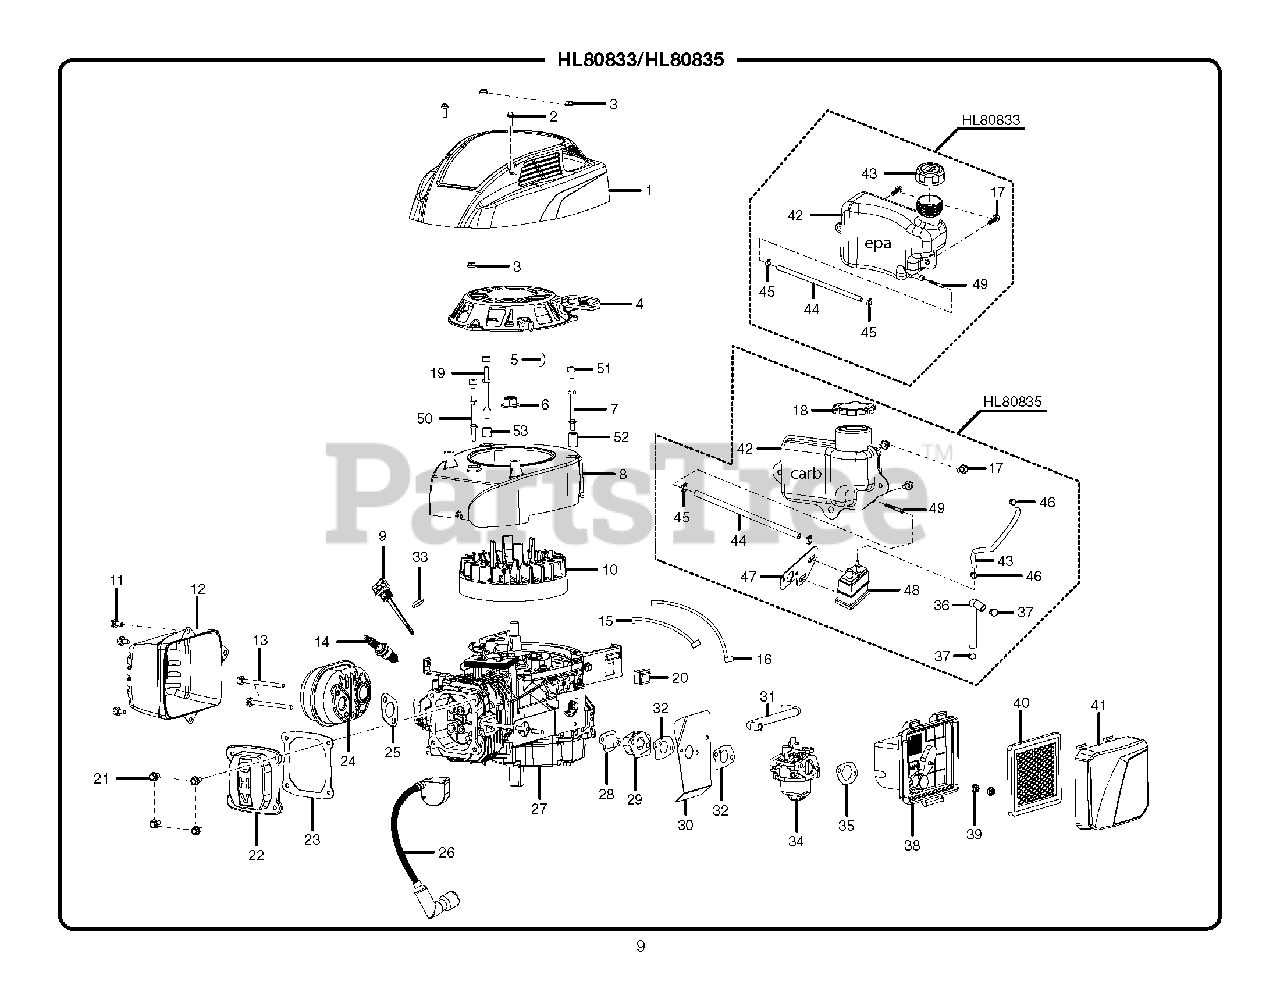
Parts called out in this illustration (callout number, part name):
1	Engine Cover
2	Bolt (Engine Cover)
3	Hex Nut (Starter)
4	Starter w/Recoil Assembly
6	Flywheel Nut
8	Engine Shroud
9	Oil Dipstick Assembly
10	Flywheel Assembly
11	Bolt (Muffler Cover)
12	Muffler Cover
13	Muffler Bolt
15	Ground Wire
17	Bolt (Fuel Tank)
18	Fuel Cap
21	Bolt (Valve Cover)
22	Valve Cover
23	Valve Cover Gasket
25	Muffler Gasket
26	Ignition Coil
27	Crankcase Assembly
28	Gasket (Insulator Plate, Inner)
29	Insulator Plate
30	Gasket (Insulator Plate, Outer)
31	Breather Tube
32	Gasket (Carburator)
34	Carburator Assembly
35	Gasket (Air Filter)
36	Hose (Air Filter)
37	Hose Clamp
38	Air Filter Case
39	Hex Nut (Air Filter)
41	Air Filter Cover
42	Fuel Tank
43	Fuel Hose
45	Clamp (Fuel Tube)
46	Clamp (Fuel Hose)
47	Bracket
48	Fuel System Collector
49	Fuel Filter
51	Bushing (Engine Shroud)
52	Bushing (Tall)
53	Bushing (Short)
